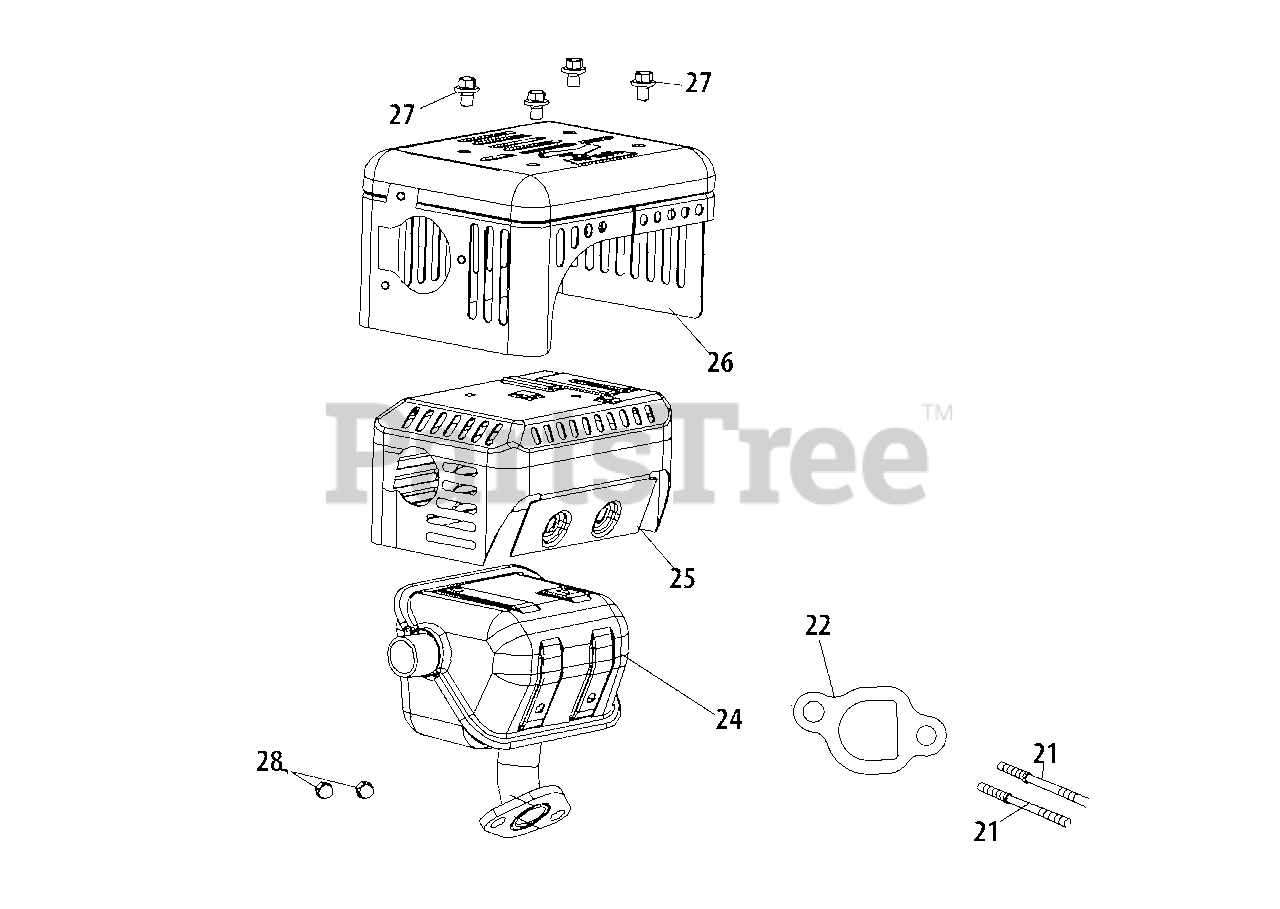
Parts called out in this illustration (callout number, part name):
21	Muffler Stud M8×34
21	Muffle Stud Kit
22	Exhaust Pipe Gasket
24	Muffler Body
25	Muffler Shield
26	Muffler Guard
27	Bolt M5×8
